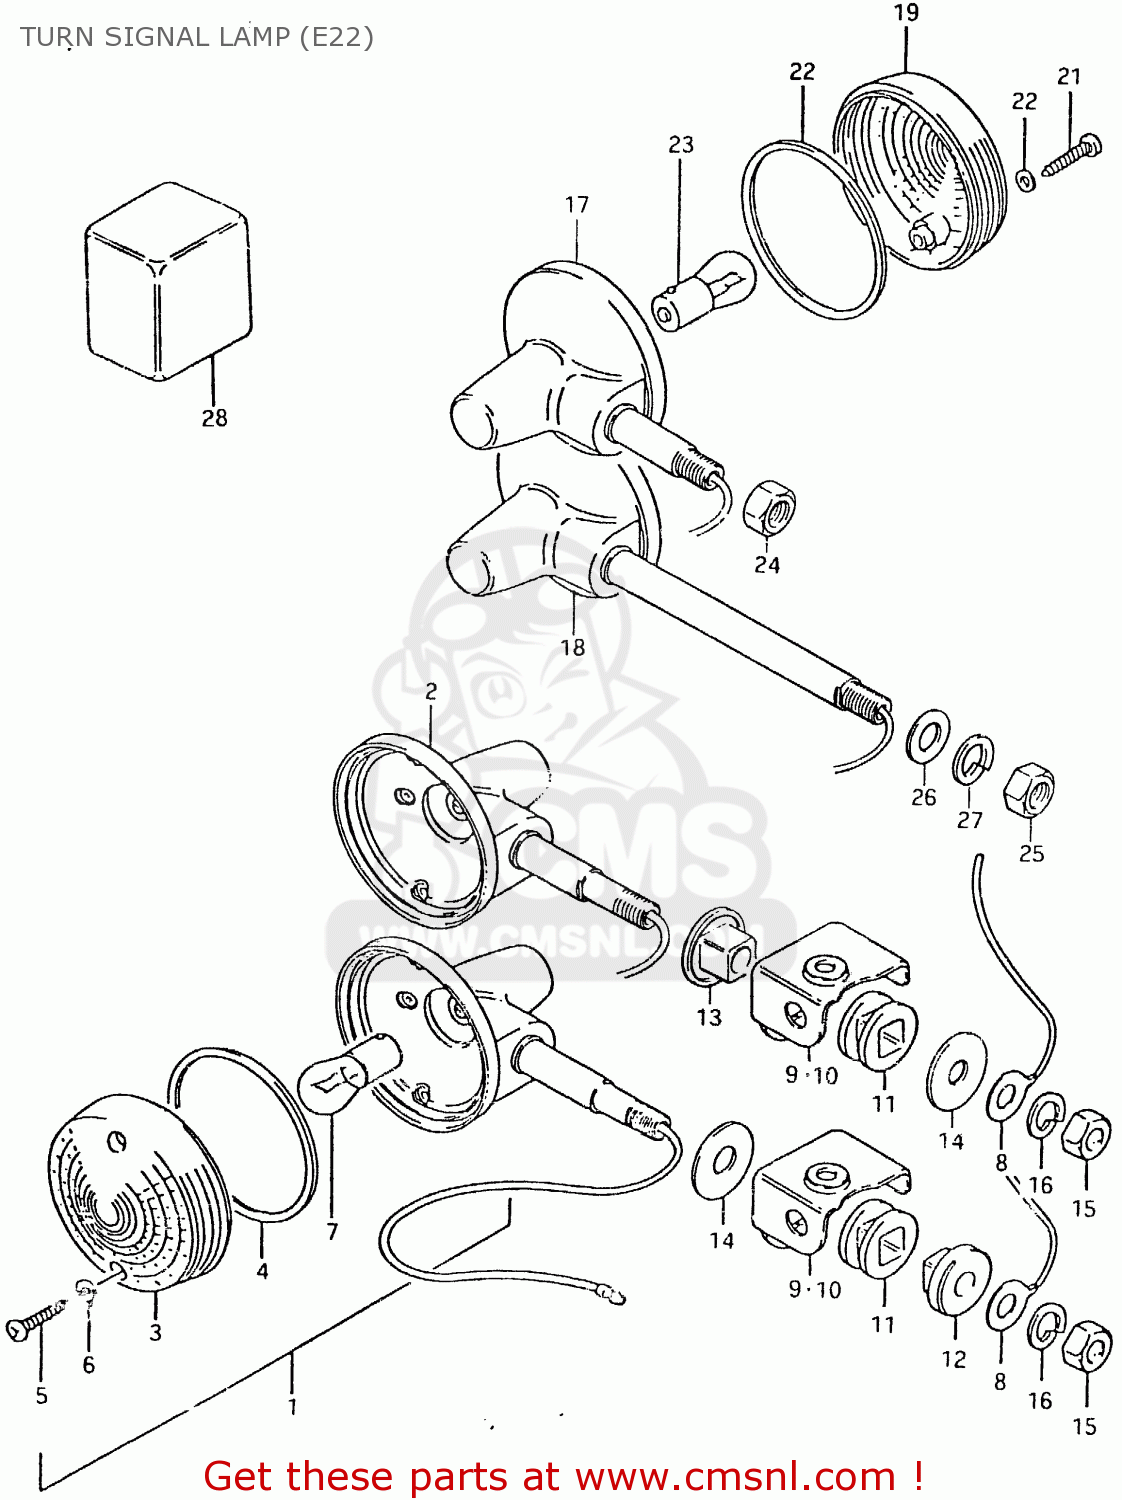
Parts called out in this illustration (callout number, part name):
1	LAMP, FRONT TURN SIGNAL
2	LAMP ASSY,FR TURN SIGNAL
3	LENS
4	GASKET (NAS)
5	SCREW
6	GASKET (NAS)
7	BULB (6V,21W)
8	LEAD WIRE,EARTH
9	BRACKET, FRONT RH
10	BRACKET, FRONT LH
11	CUSHION
12	SPACER,RR TURNSIGNAL LAMP
13	SPACER
14	WASHER (10.5X30X2.3)
15	NUT
16	LOCK WASHER
17	LAMP, REAR TURN SIGNAL
18	LAMP, REAR TURN SIGNAL
19	LENS
20	GASKET (NAS)
21	SCREW
22	GASKET (NAS)
23	BULB (6V,21W)
24	NUT
25	NUT
26	WASHER
27	LOCK WASHER
28	RELAY, TURN SIGNAL
